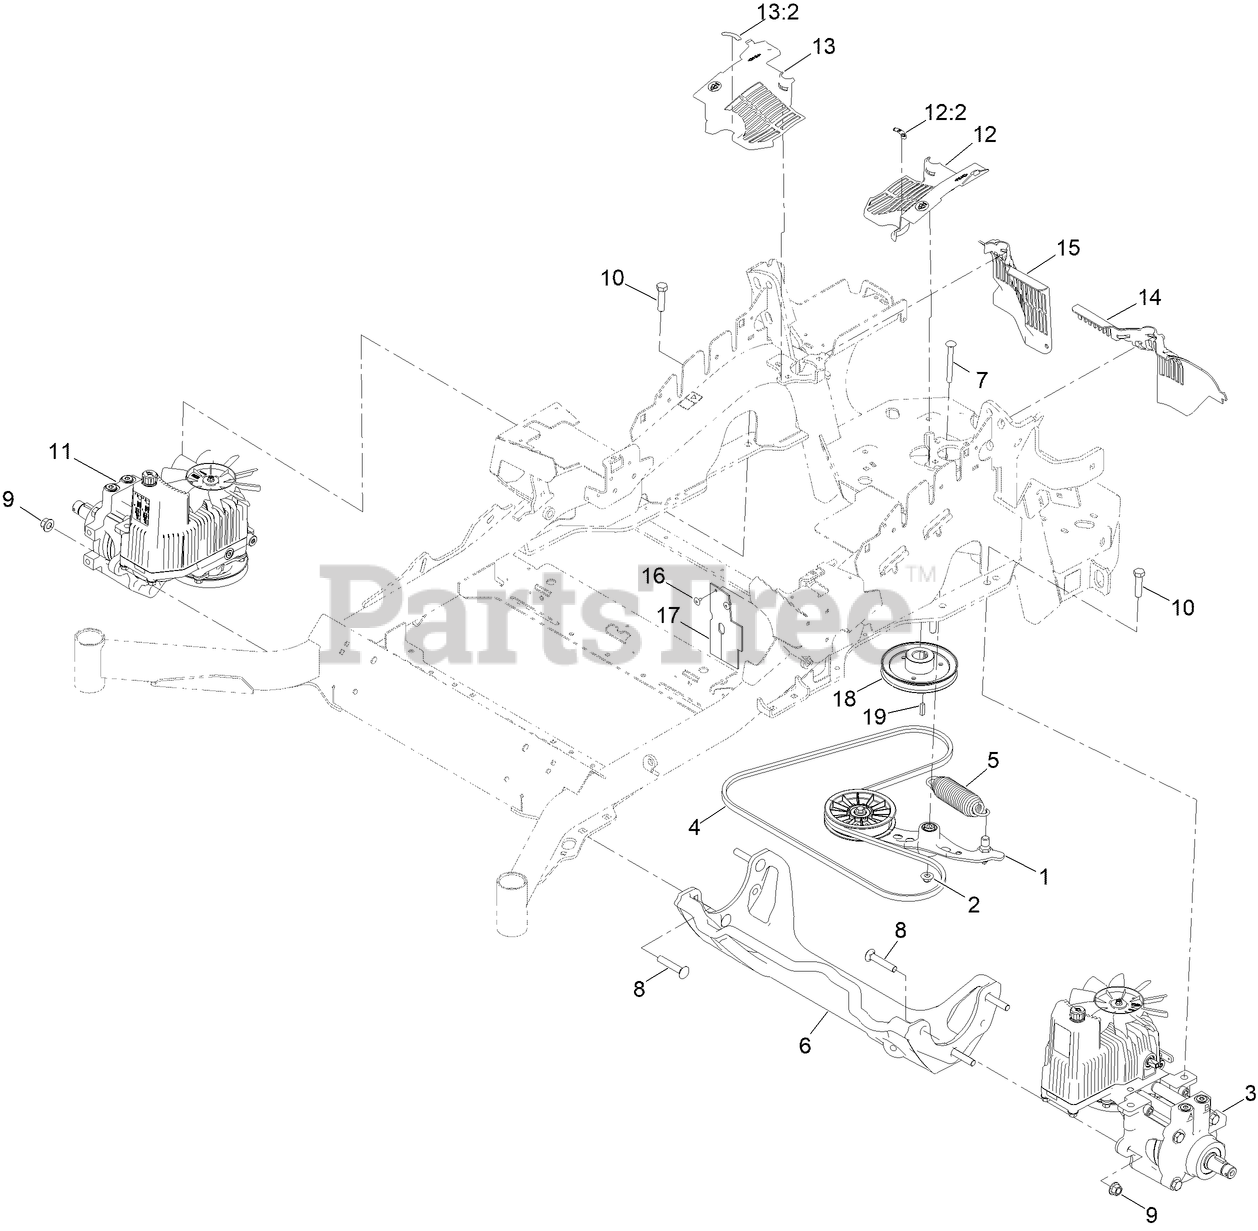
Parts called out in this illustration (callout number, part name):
1	PUMP IDLER ASM
2	NUT-FLANGE, NI
3	HYDRO-LH
4	BELT-V
5	SPRING-EXTENSION
6	CRADLE-HYDRO
7	BOLT-SHOULDER, CARRIAGE
8	SCREW-CARR
9	NUT-LOCK
10	SCREW-HH
11	HYDRO-RH
12	LH HYDRO GUARD ASM
12:2	DECAL-OIL, HYDRO
13	RH HYDRO GUARD ASM
13:2	DECAL-OIL, HYDRO
14	GUARD-HYDRO, REAR LH
15	GUARD-HYDRO, REAR (RH)
16	RIVET-POP
17	DEFLECTOR-AIR FLOW
18	SHEAVE
99	FILTER-HYDRO
